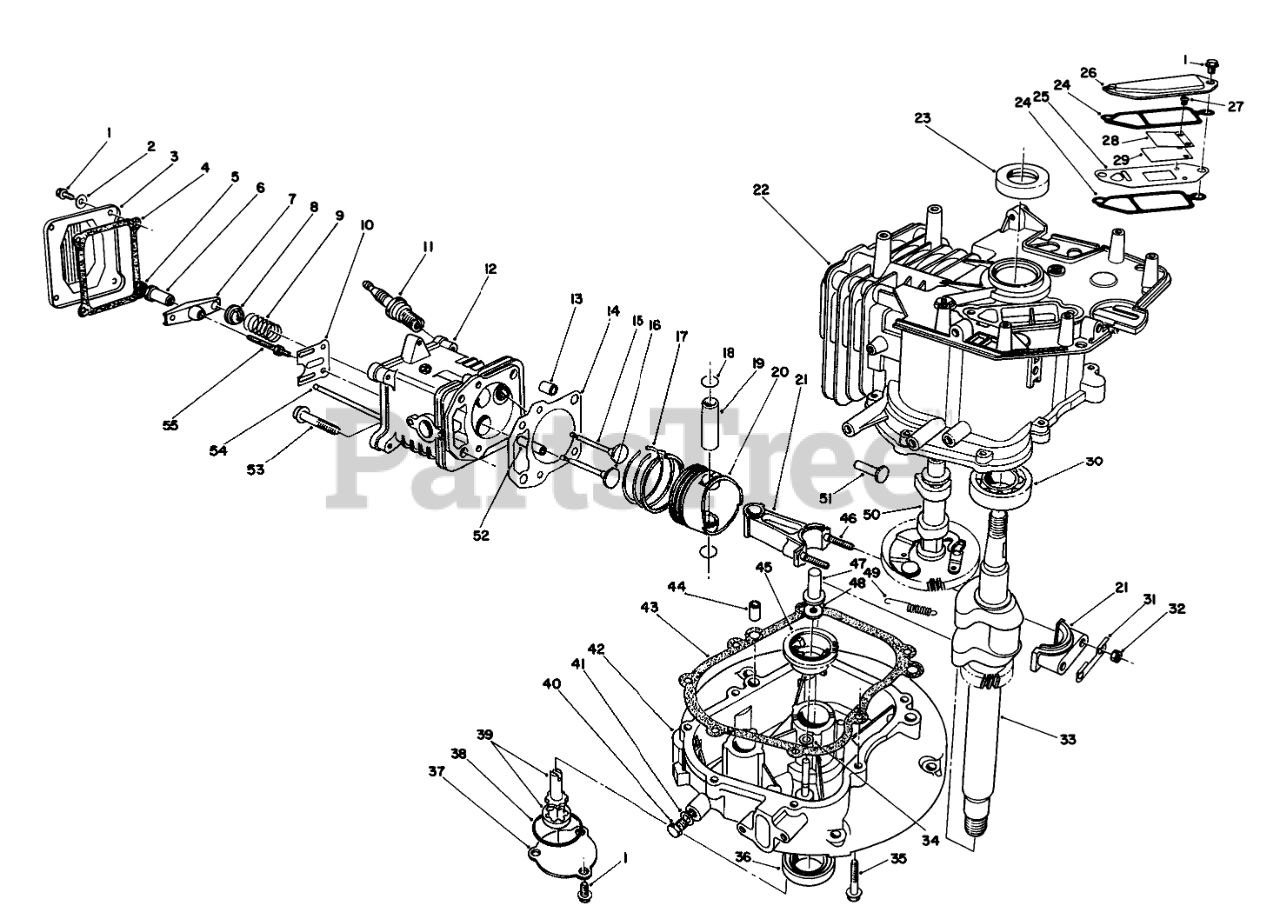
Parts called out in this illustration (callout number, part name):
2	WASHER
3	COVER
4	GASKET
6	PIVOT
8	RETAINER
9	SPRING
10	GUIDE
11	SPARK PLUG
12	Head-Cylinder (Incl. Ref. #52)
14	GASKET
15	VALVE-EXHAUST
16	VALVE-INTAKE
17	RING SET
18	CIRCLIP
20	PISTON
21	Connecting Rod Assembly (Incl. Ref. #31, 32 & 46)
22	Block-Engine (Incl. Ref. #23 & 30)
24	GASKET
25	Plate-Breather
26	COVER
27	Screw-Reed Valve
28	Retainer-Reed Valve
29	Valve-Reed
30	BEARING
31	Plate-Lock
33	CRANKSHAFT
34	WASHER
37	COVER
38	O-RING
39	OIL PUMP
40	OIL DRAIN PLUG
41	GASKET
42	Crankcase
43	GASKET
45	GOVERNOR FLYWEIGHT ASM
47	PLUNGER
48	WASHER
49	SPRING
50	Camshaft Assembly (Incl. Ref. #49)
51	TAPPET
52	GUIDE
